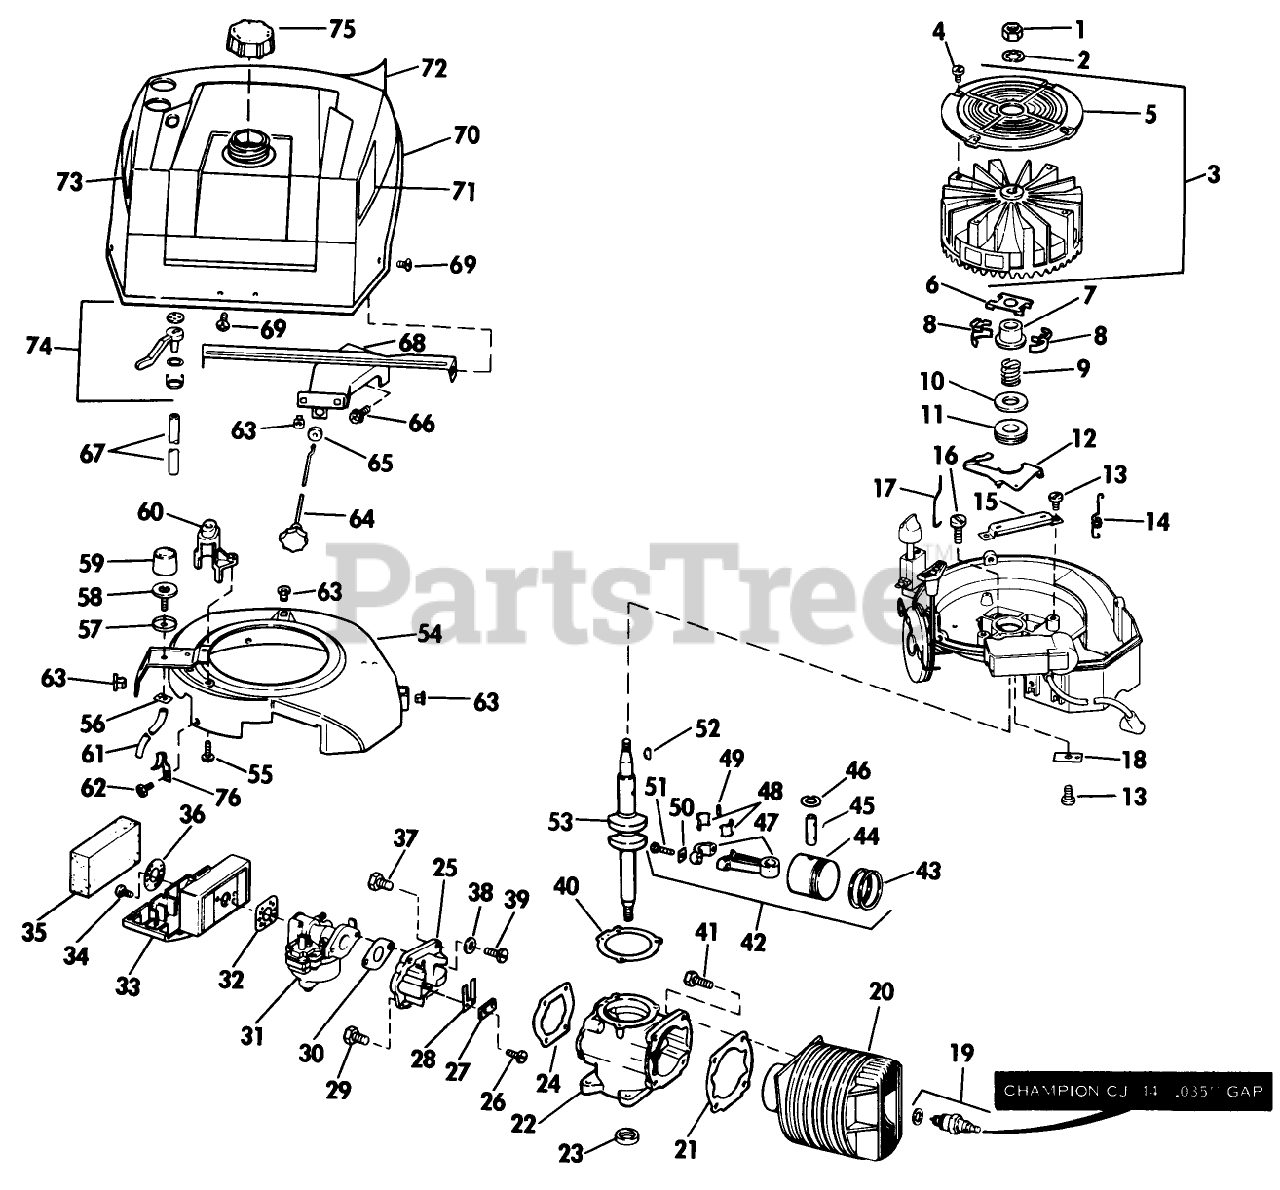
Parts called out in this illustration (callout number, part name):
4	SCREW F
7	COLLAR S
9	SPRING S
12	LEVER-GOVERNOR S
13	SCREW S
15	BRACKET
19	Spark Plug-Champion CJ-14 .035" Gap
21	GASKET S
24	GASKET S
25	REED PLATE AY. S
27	PLATE-BACKUP, REED
29	SCREW S
30	GASKET S
32	GASKET S
34	SCREW S
35	AIR FILTER S
36	WASHER S
37	SCREW S
40	GASKET S
46	RING-RETAINING
48	LINER ASM
56	LOCKNUT S
57	CUP-BULB
63	NUT-CLIP
66	SCREW S
68	BRACKET
69	SCREW S
